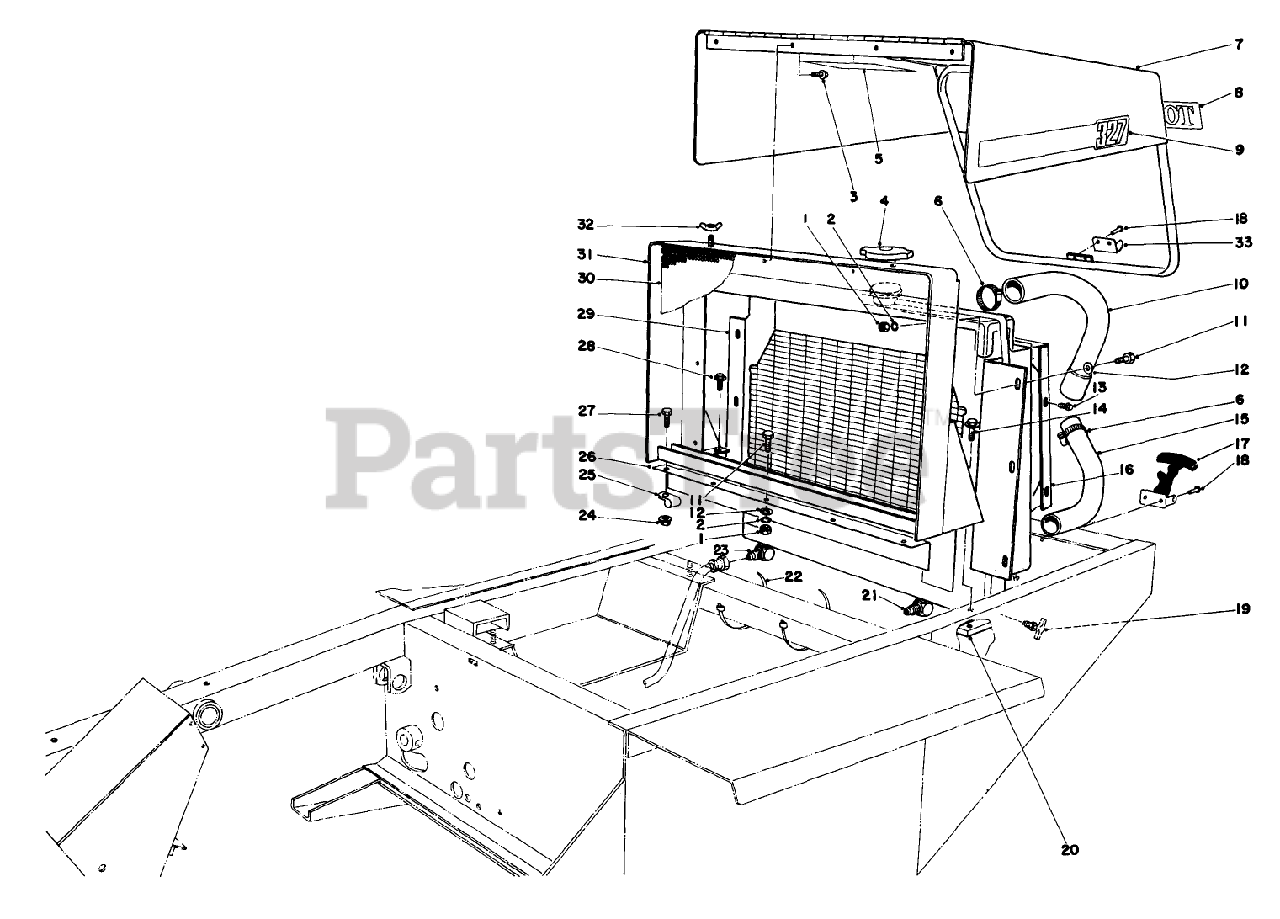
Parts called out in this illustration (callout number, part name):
1	NUT-HEX
2	WASHER-LOCK
3	SCREW
4	RAD PRESS CAP ASM
5	Decal
6	CLAMP-HOSE
7	Hood
8	Decal
9	DECAL-GM 327
10	UPPER HOSE
11	SCREW-HH
12	WASHER-PLAIN
13	SCREW-HHFTF
14	SCREW-HHF
15	LOWER HOSE
16	RAD SHROUD WA B
17	Draw Latch
18	RIVET
19	DRAINCOCK
20	LH FRAME BAR
21	ELBOW
22	TIE-CABLE
23	ELBOW
24	NUT-HF
25	CLAMP-R
26	Sealing Plate Grill
27	SCREW-HH
28	SCREW-HWHTF
29	RADIATOR
30	GRILLE WA R
31	Radiator Support
32	NUT-WING
33	Keeper
